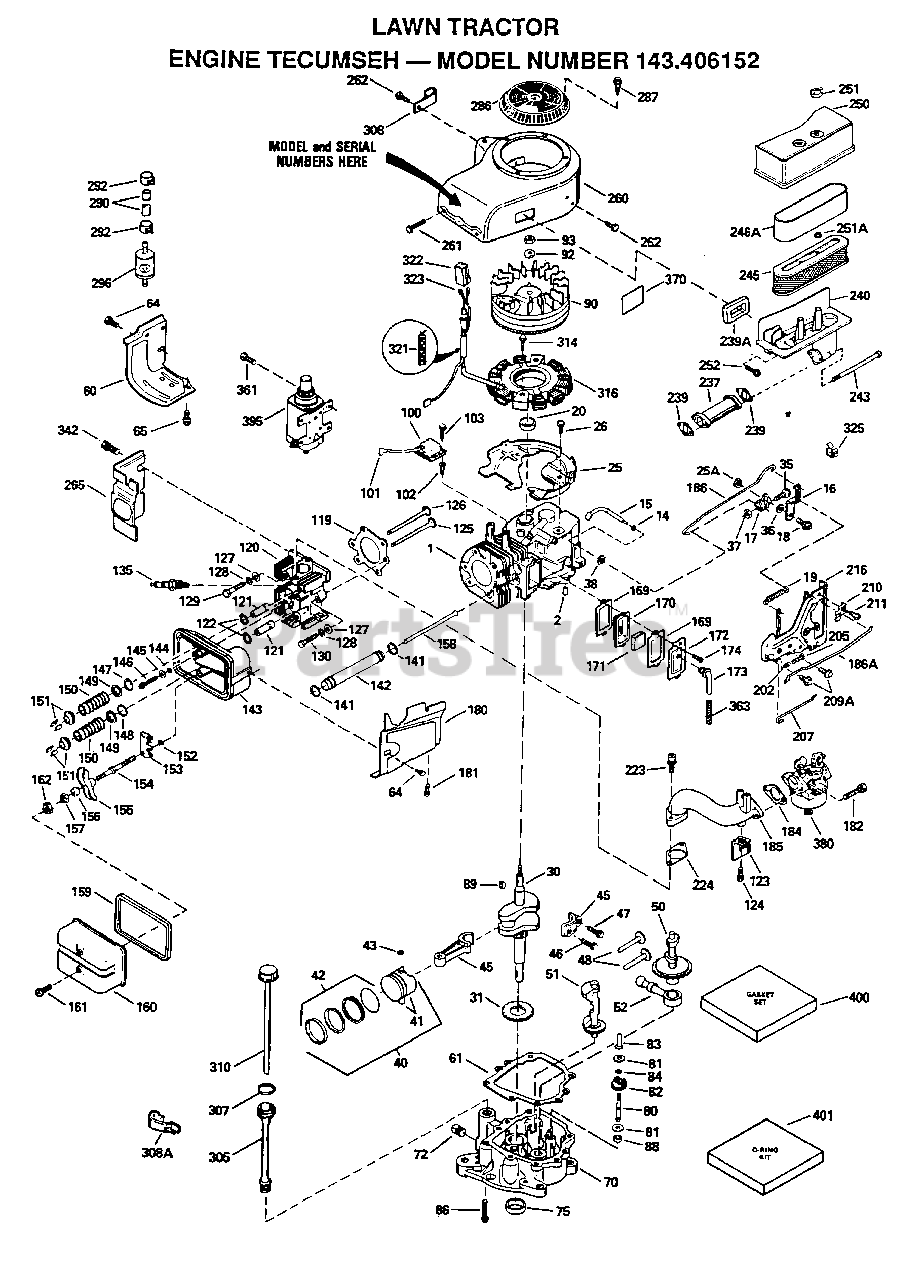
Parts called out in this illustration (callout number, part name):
224	GASKET, INTAKE PIPE
237	ADAPTER, AIR CLEANER
239	GASKET, AIR CLEANER ELBOW
239A	GASKET, AIR CLEANER-TO-HOUSING
240	BODY ASSY, AIR CLEANER
245	ELEMENT, AIR CLEANER
246A	FILTER, POLY PRE-CLEANER
250	COVER, AIR CLEANER
251	NUT, WING
251A	NUT & LOCKWASHER
260	HOUSING, BLOWER
265	COVER, CYLINDER HEAD
286	SCREEN, DEBRIS
290	LINE, FUEL
292	FUEL LINE CLAMP
296	FILTER, FUEL
305	TUBE, OIL FILL
308	CLIP, OIL FILL TUBE
308A	CLIP, OIL FILL TUBE
310	DIPSTICK, OIL
316	COIL ASSY, ALTERNATOR
321	DIODE
322	CONNECTOR, BODY
323	TERMINAL, FEMALE
325	CLIP, WIRE
363	SPRING, COIL
370	DECAL, INSTRUCTION
380	CARBURETOR
395	STARTER MOTOR
400	GASKET SET
401	O-RING KIT
